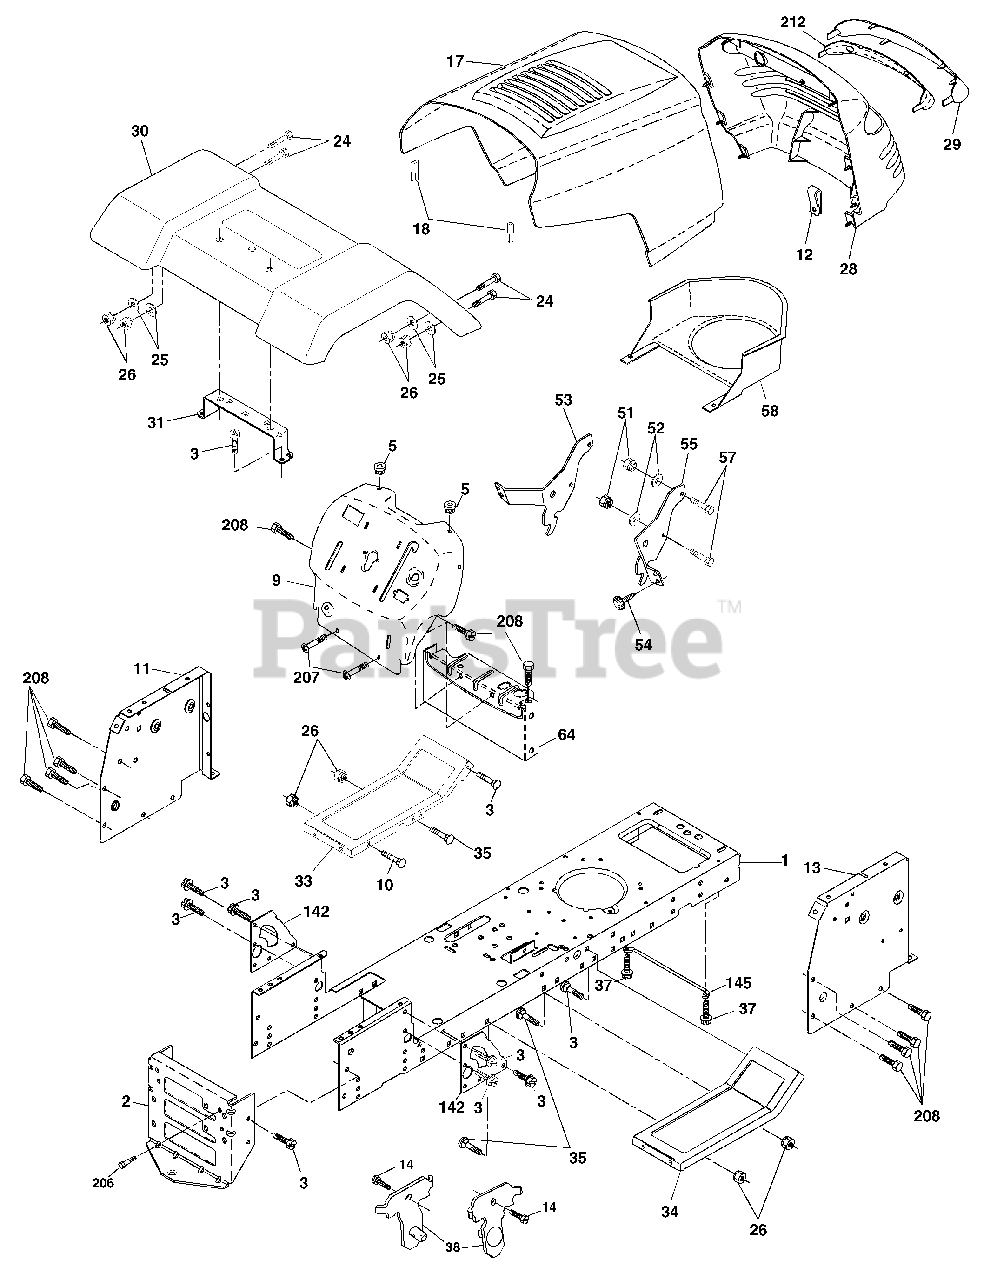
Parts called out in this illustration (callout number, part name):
1	Chassis
2	Drawbar, Stretch
3	Screw 3/8-16 x 3/4
5	Bumper, Hood/Dash
10	Bolt, Carriage 3/8-16 x 1
11	Panel Dash LH
12	Clip Tinnerman Grille P.L
13	Panel Slkscr Dash RH
14	Screw Thdrol 3/8-16 x 1/2
17	Hood
18	Bumper Hood
24	Bolt Fin Hex 3/8-16unc X 1 Gr. 5
25	Washer 13/32 X 13/16 X 12 Ga
26	Nut Lock Hex w/Ins 3/8-16 Unc
28	Grille/Lens Asm.
29	Lens Grille Private Label
30	Fender
31	Bracket Fender Repl 109873x
33	Footrest Pnt LH
34	Footrest Pnt RH
35	Bolt Rdhd Sht Sqnk 3/8-16 X3/4
37	Screw Thdrol 5/16-18 x 1/2 TYT
38	Bracket Asm. Pivot Mower
51	Nut Lock W/Insert 1/4-20unc
52	Washer 9/32 x 7/8 x 16 Ga.
53	Bracket Grille Lh
54	Screw Hex 8-18 x 7/8
55	Bracket Grille Rh
57	Bolt Fin Hex 1/4-20 unc x .75
58	Duct Air Engine PL/LT
64	Dash Lower
142	Plate Reinforcement
145	Rod Pivot Chassis/Hood
206	Bolt Shoulder 5/16-18
207	Screw Thdrol 5/16-18 x 1/2
208	Screw Thdrol 3/8-16 x 1/2
212	Insert Lens Reflect
